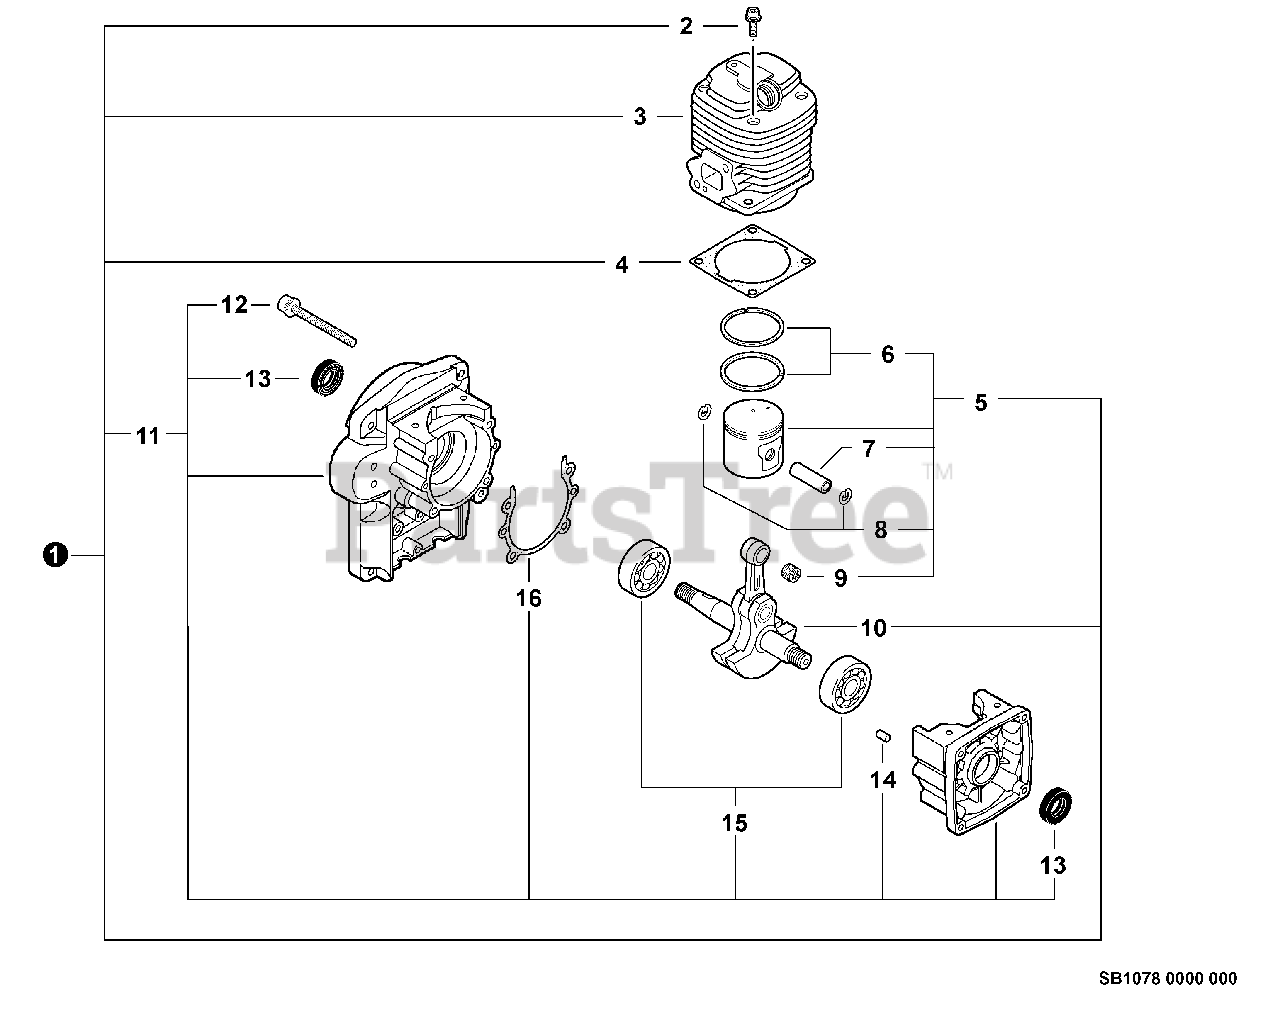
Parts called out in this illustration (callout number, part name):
1	SHORT BLOCK -- SB1078
2	SCREW - 5X22
3	CYLINDER
4	GASKET, CYLINDER
5	PISTON KIT
6	RING, PISTON
7	PIN, PISTON
8	RING, RETAINING - 8
9	BEARING, NEEDLE
10	CRANKSHAFT ASSY
11	CRANKCASE KIT
12	SCREW - 5X40
13	SEAL, OIL
14	PIN - LOCATING
15	BEARING, BALL - 6202
16	GASKET, CRANKCASE
